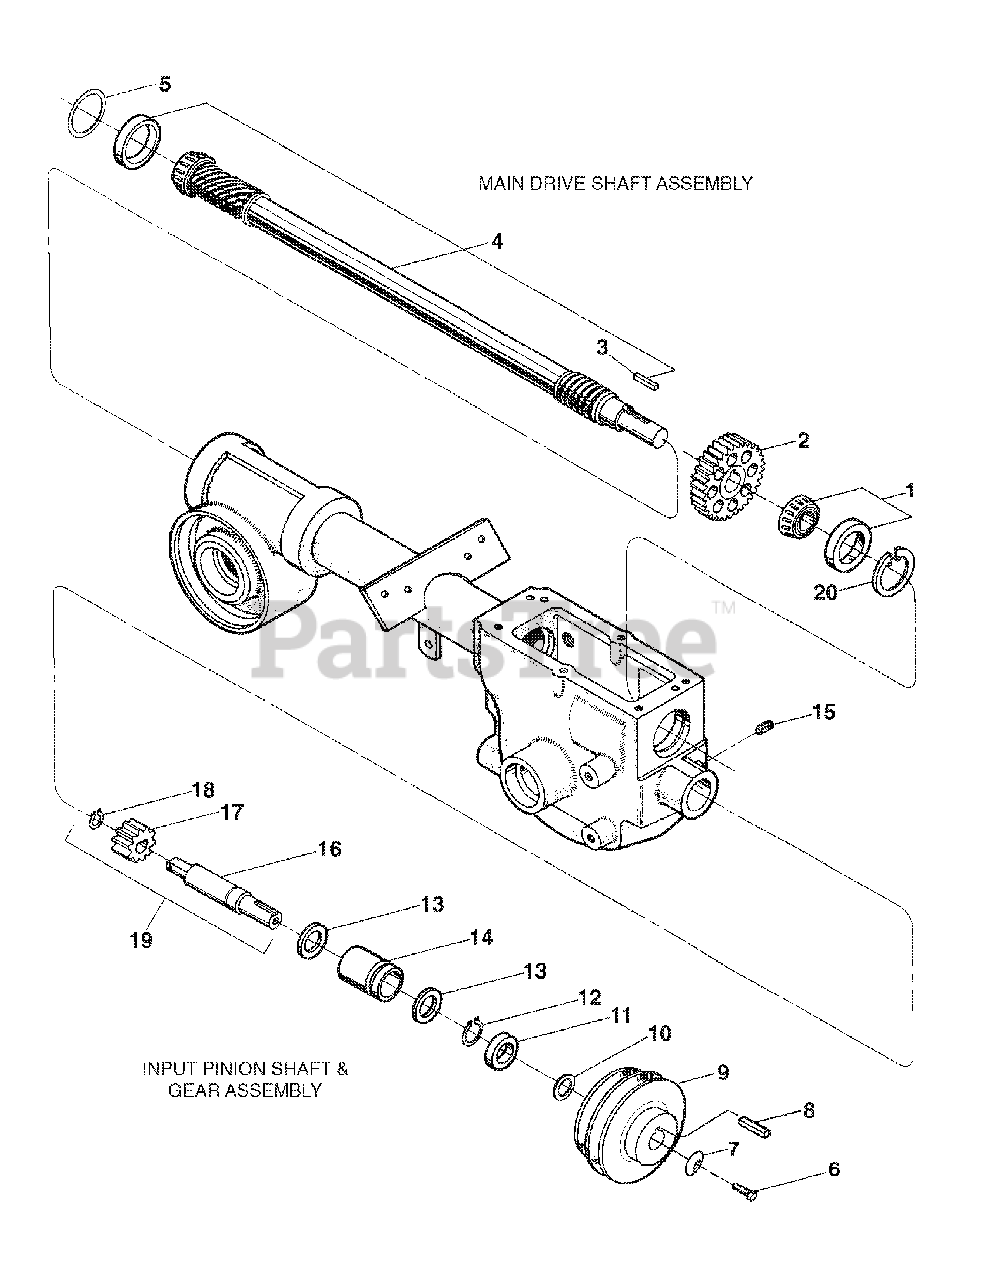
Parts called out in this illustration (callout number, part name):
1	Bearing, Tapered Roller with Race
2	Spur Gear
3	Key, 3/16 sq. x 1
4	Main Drive Shaft, Also incl. Pressed-on GW-1714 & GW-9301
5	Shim, Rear Bearing Cap, .010" thick
5	Shim, same as above, but .030" thick
5	Shim, same as above, but .005" thick
5	Shim Set (Incl. two GW-1224-1; two 1224-2 & one GW-1224-3
6	Hex Hd. Screw, 5/16-24 x 1-1/8
7	Washer, Disc Spring (concave suface faces pulley)
8	Key, 3/16 sq. x 1-1/2
9	Transmission Drive Pulley
10	Support Washer
11	Oil Seal, Input Pinion Shaft
12	Retaining Ring (external)
13	Thrust Washer
15	Set Screw, 5/16-18 x 3/8
16	Input Pinion (steel shaft)
17	Input Pinion Gear
18	Retaining Ring (external)
19	Pinion Assy. (Incl. one each Refs. 16, 17 & 18
20	Retaining Ring (internal)
